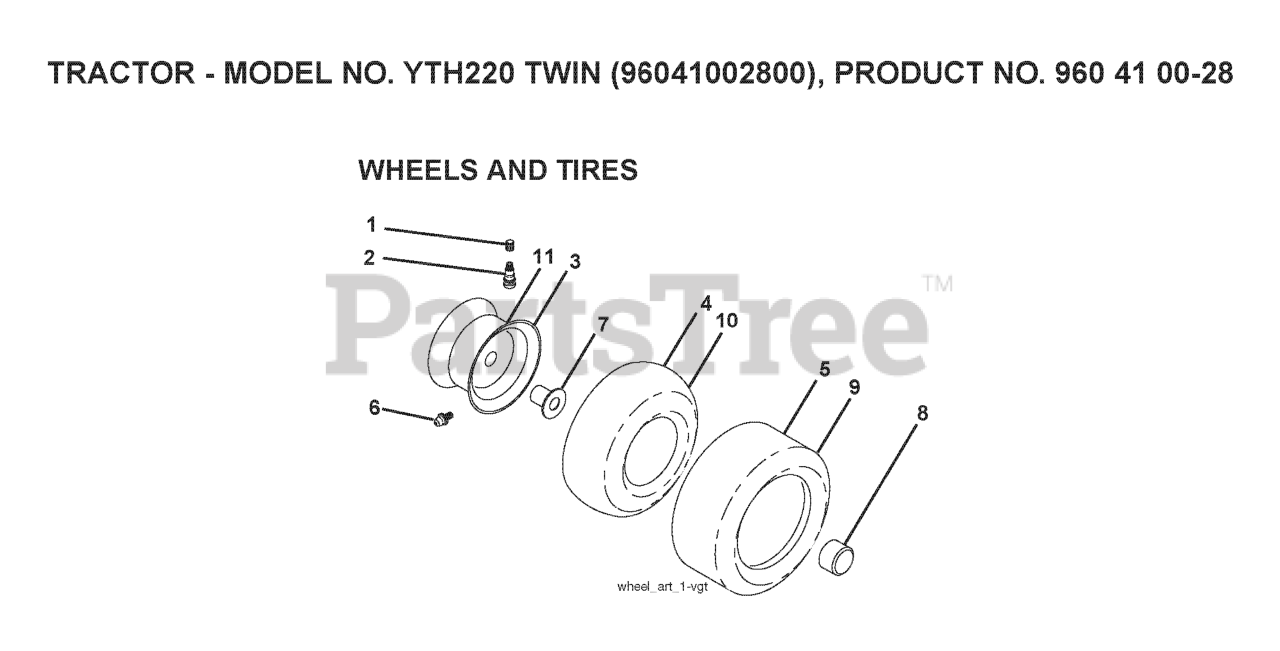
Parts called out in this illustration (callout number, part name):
2	VALVE STEM LT
3	RIM ASSEMBLY, FRONT
4	TUBE.16X6.5/7.5-8
5	TIRE HEAVY DUTY
6	FITTING LT
7	BEARING T
8	CAP, AXLE BLK
9	TIRE.22X9.50-12.TURF.SAVER.REA
10	TUBE.23X9.5-12
11	RIM.ASM.12".REAR.SILVER
